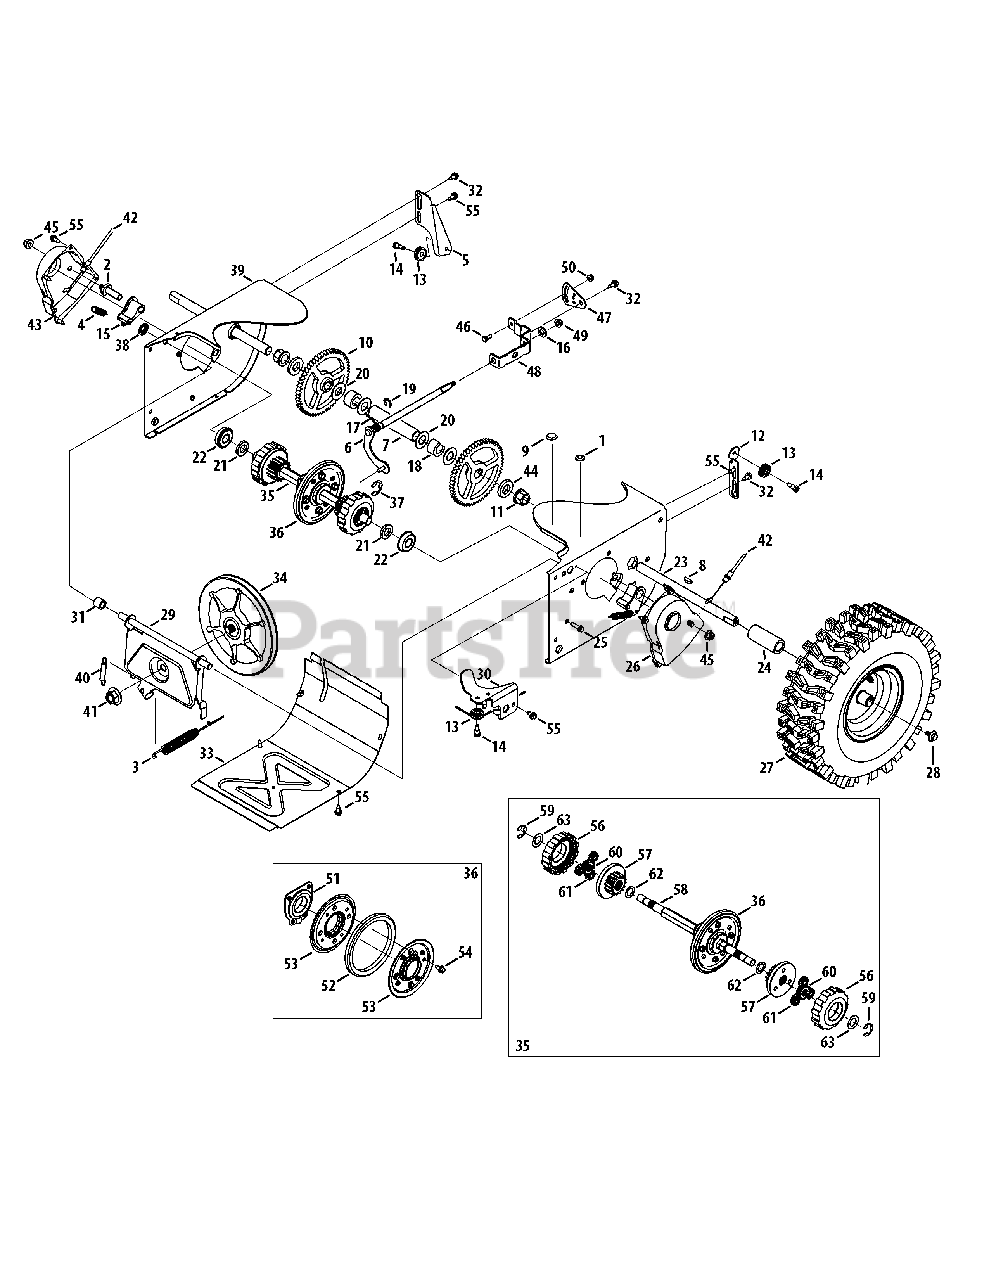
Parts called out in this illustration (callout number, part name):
1	Plug, 3/8 ID
2	Actuator Shaft
3	Drive Clutch Cable
4	Extension Spring
5	Drive Clutch Cable Guide Bracket
6	Shift Rod Assembly
7	Axle Support Tube
8	Hi Pro Key
9	Plug, 1/2 ID
10	Gear, 56T
11	Hex Flange Bearing
12	Auger Clutch Cable Guide Bracket
13	Cable Roller
14	C Screw, 1/4-28 x 0.375
15	Dogg Assembly - LH
15	Dogg Assembly - RH
16	Washer, Flat
17	Torsion Spring, .750 ID x .968 Lg.
18	Spacer
19	E Ring
20	Flat Washer, .76 x 1.49 x .06
21	Spacer
22	Ball Bearing 17 x 40 x 12
22	Ball Bearing .5625 x 1.375 x .4375
24	Spacer
25	TT Screw, 1/4-20 x 1.0
26	Shaft Retainer, LH (w/.8125 diam hex shaft)
26	Shaft Retainer, LH( w/.75 diam hex shaft)
27	Wheel Complete - LH
27	Wheel Complete - RH
28	Screw, 5/16-24 x 0.75
29	Friction Wheel Support Brkt. Assy.
30	Auger Cable Guide Bracket
31	Spacer
32	Shoulder Screw
33	Frame Cover
34	Friction Wheel Disc Assembly
35	Drive Shaft Assembly (w/.8125 diam hex shaft)
35	Drive Shaft Assembly (w/.75 diam hex shaft)
36	Friction Wheel Assembly
37	Retainer Ring
38	Speed Nut
39	Wheel Drive Frame
40	Extension Spring
41	Flange Nut, 5/8-18
42	Steering Cable
43	Shaft Retainer, RH (w/.8125 diam hex shaft)
43	Shaft Retainer, RH( w/.75 diam hex shaft)
44	Axle Spacer
45	Flange Lock Nut, 3/8-16
46	Hex Screw, 1/4-20 x .620
47	Speed Selector Pivot Bracket
48	Speed Selector Shift Bracket
49	Flange Lock Nut, 5/16-18
50	Flange Lock Nut, 1/4-20
51	Friction Wheel Bearing Assembly
52	Friction Wheel
53	Friction Plate
54	Screw, 5/16-18 x .750
55	AB Screw, 1/4-20 x 0.625
56	Gear Assembly, Plantry Ring
57	Carrier Assembly, Plantry Ring
58	Shaft, Strbl Drv Hex, .812
59	E-Ring
60	Gear, Sun, 18T
61	Gear, 12T
62	Washer, Thrust, .75 x 1.25 x .03
63	Flat Washer .67 x 1.174 x .02 (4 Used)
63	Flat Washer .580 x 1.125 x .080 (2 Used)
